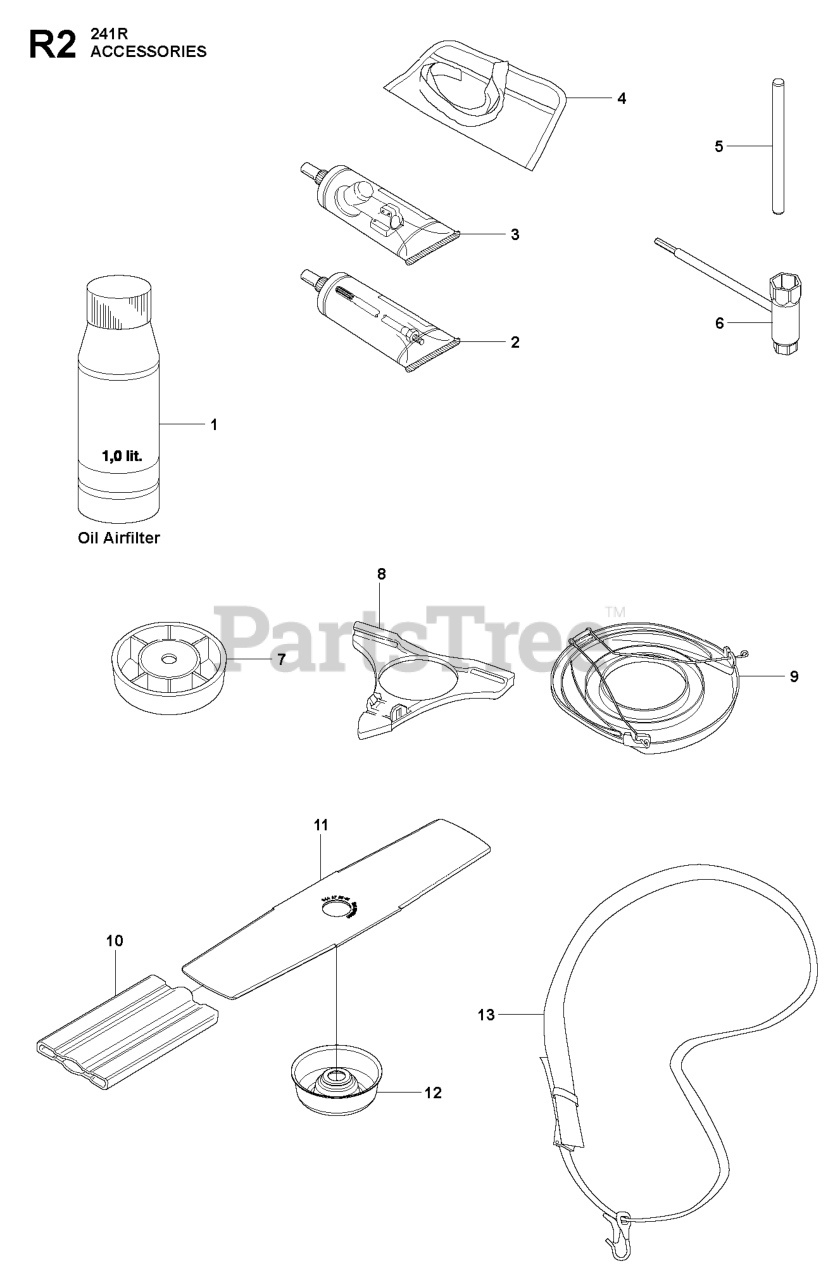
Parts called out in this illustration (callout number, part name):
1	Air Filter Oil 1l.
2	DRIVE SHAFT GREASE (200 G)
3	BEVEL GEAR GREASE
5	LOCKING PIN
6	RP COMBI TOOL
7	SUPPORT CUP
8	TRANSPORT GUARD
9	BLADE GUARD TRANSPORT
12	SUPPORT CUP
13	Harness-w/o warning
